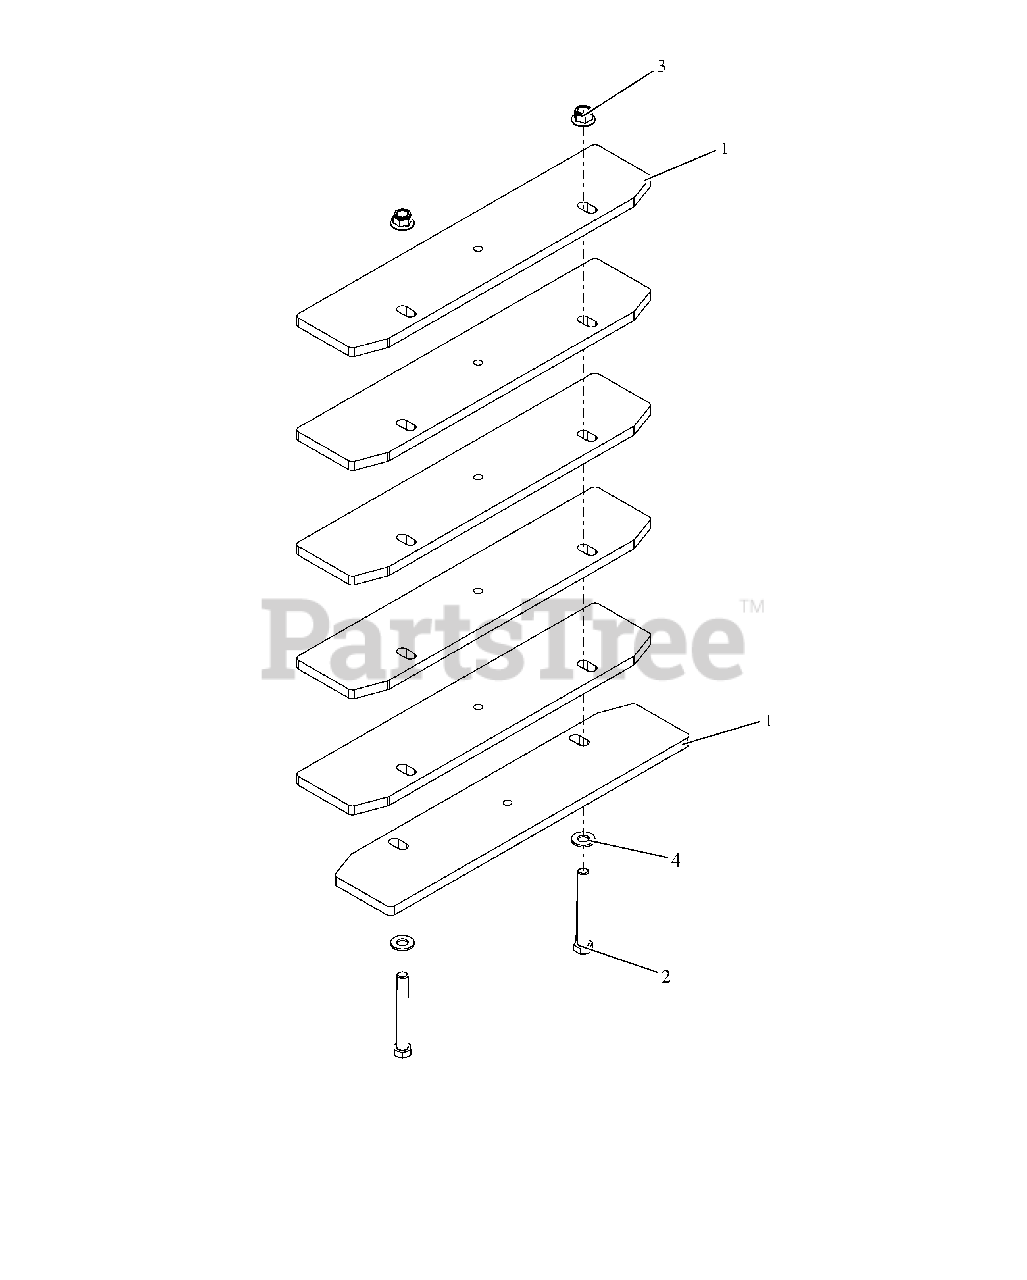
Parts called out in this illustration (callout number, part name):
1	PLATE, COUNTER WEIGHT
2	@BLT-HEX .50-13X4.00 GR5 YWZC
3	@NUT-LK-NYL-FLG .50-13 YWZC
4	@WSHR-FL-STL.531X1.06X.095YWZC
